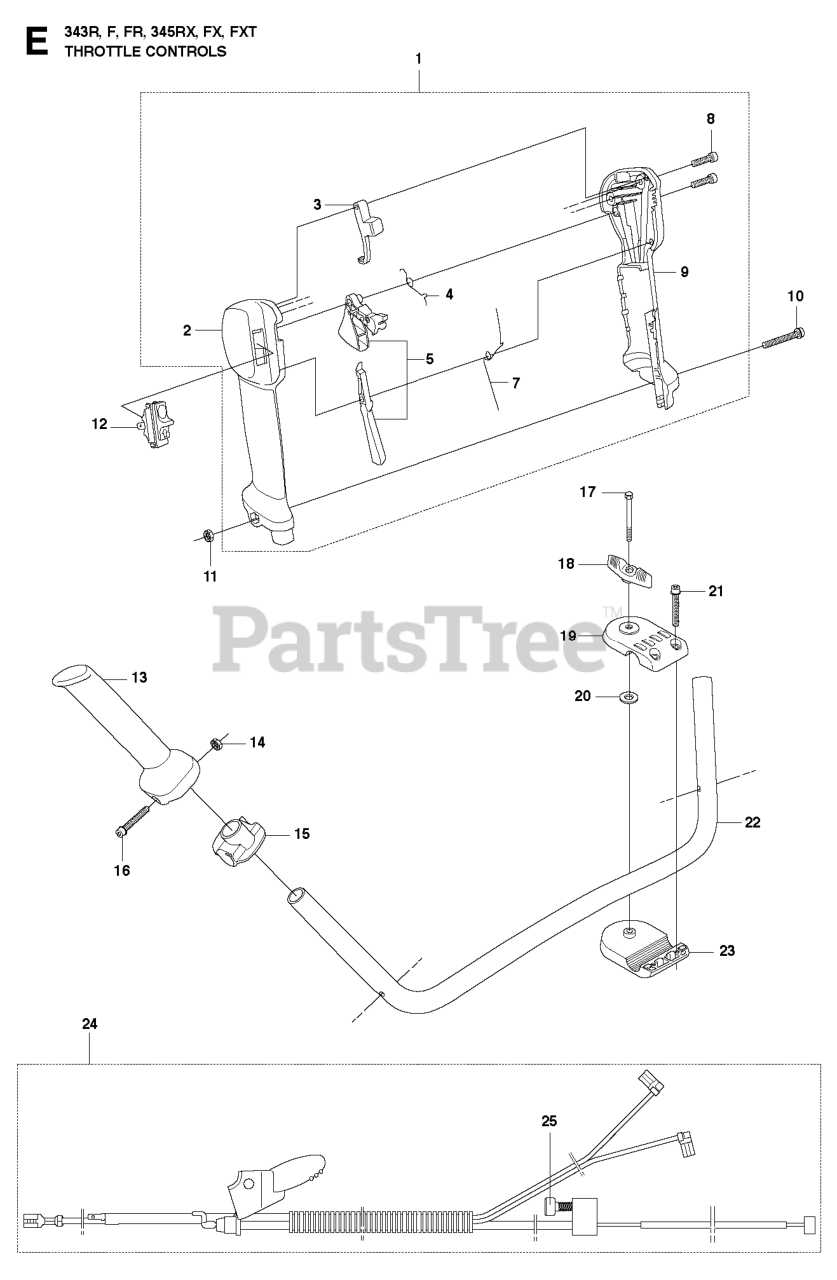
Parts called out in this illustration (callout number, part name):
1	THROTTLE HANDLE ASSY
2	HANDLE HALF LEFT
3	LOCKOUT STARTER THROTTLE
5	THROTTLE CONTROL
9	HANDLE HALF RIGHT
10	SCREW
12	STOP BUTTON
14	NUT M6M M5
17	WASHER - 26X6.5X1.6
19	HANDLE HOLDER UPPER
23	HANDLE HOLDER LOWER
24	WIRING ASSY
25	SCREW
